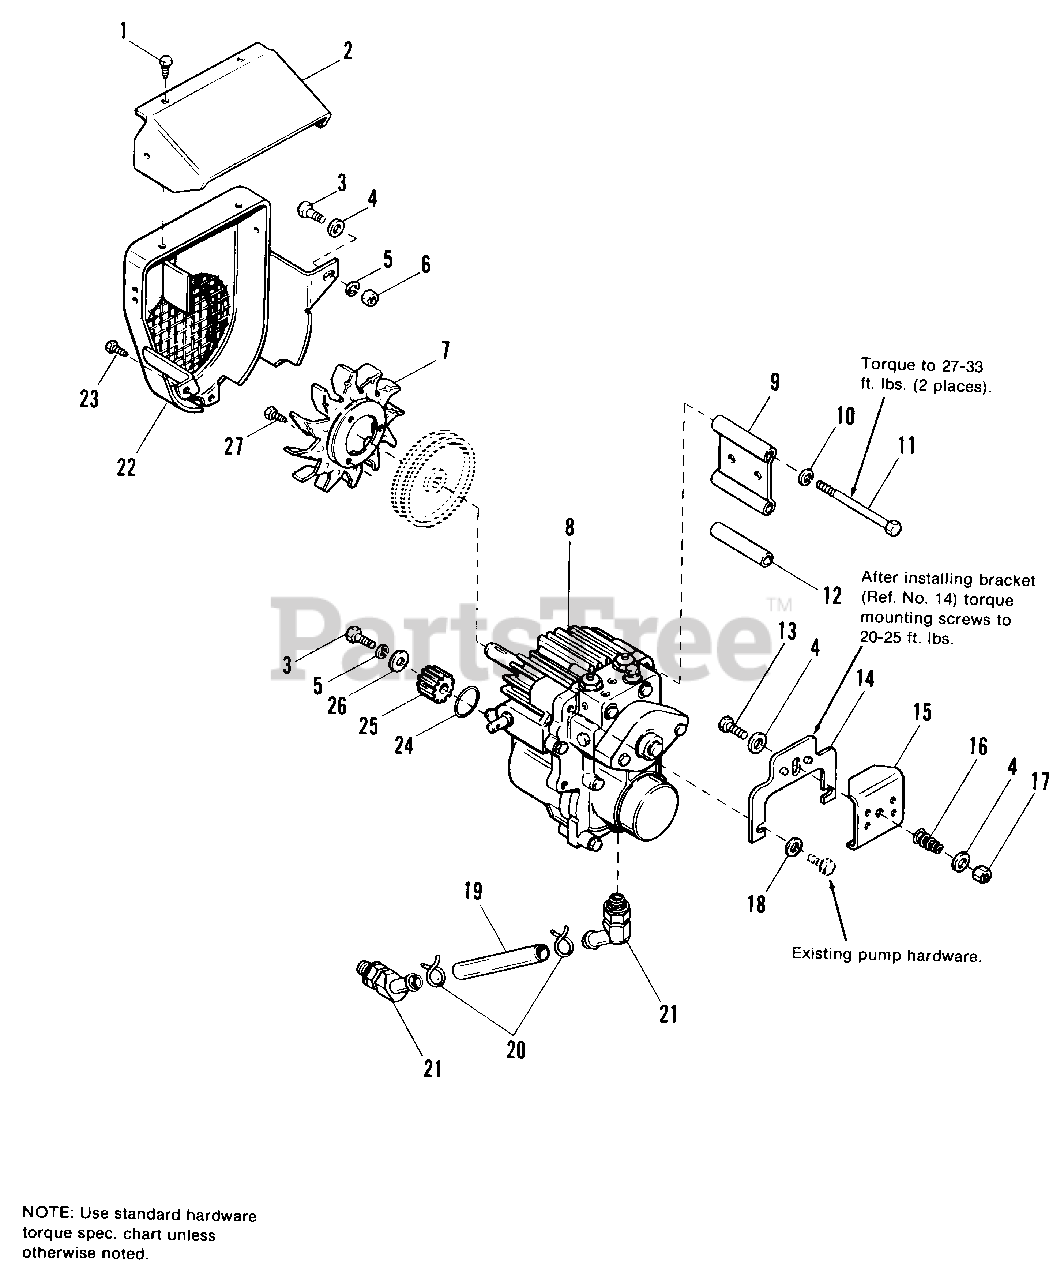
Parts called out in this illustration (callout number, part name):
1	SCREW, Self-Tapping, #10 x 3/8
2	DEFLECTOR, Shroud
3	CAPSCREW, Hex Hd., 5/16-18 x 3/4
4	WASHER, Plain, 5/16
5	LOCKWASHER, 5/16
6	NUT, Hex, Full, 5/16-18
7	FAN, Pulley
8	HYDROSTATIC PUMP & MOTOR UNIT
10	LOCKWASHER, 3/8
11	CAPSCREW, Hex Hd., 3/8-16 x 5
12	SPACER
13	CAPSCREW, Hex Hd., 5/16-18 x 1
15	LATCH, Release
17	LOCKNUT, Hex, 5/16-18
19	HOSE, Inlet
20	CLAMP, Hose
21	ELBOW, Hose Fitting
22	SHROUD ASSY., w/Screen
23	SCREW, Hex, Washer Hd., Taptite, 5/16-18 x 3/4
25	PINION, Motor Shaft
27	SCREW, Hex, Washer Hd., Taptite, 1/4-20 x 3/8
